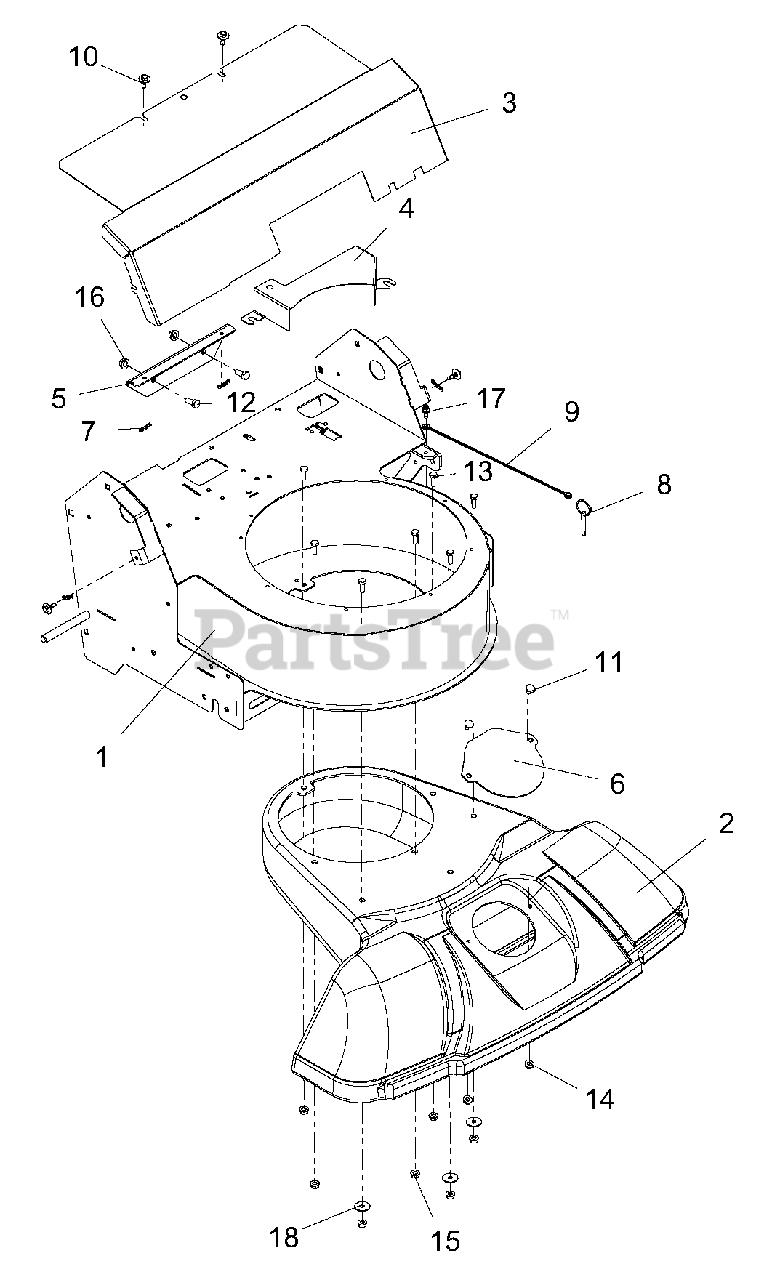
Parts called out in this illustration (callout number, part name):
1	KIT, APV FRAME ARIENS W/DECAL
2	INLET-MOLDED, APV FRONT
3	GUARD, TRANSMISSION - APV
4	GUARD, BELT - APV
5	BRKT, SUPPORT - TRANS GUARD
6	COVER, HOSE INLET
7	PIN-HAIR, ENDRIES #25 YWZC
8	PIN, RING DETENT .25X1.50 ZC
9	CBL,HOOD
10	SCR-TAP .25-20X.5 CAPTIVE
11	BLT-RDHDSQSHNK.25-20X.50 YWZC
12	@BLT-HEX .31-18X.75 GR5 YWZC
13	@BLT-HEX .25-20X.75 GR5 YWZC
14	@NUT-LK-CTR-FLG .25-20 YWZC
15	@NUT-LK-TOP-FLG .25-20 YWZC
16	@NUT-LK-TOP-FLG .31-18 YWZC
17	SCR-TAP .25-20X.50 HWH TR YWZ
18	WSHR-FL-STL .281X1.000X.063
